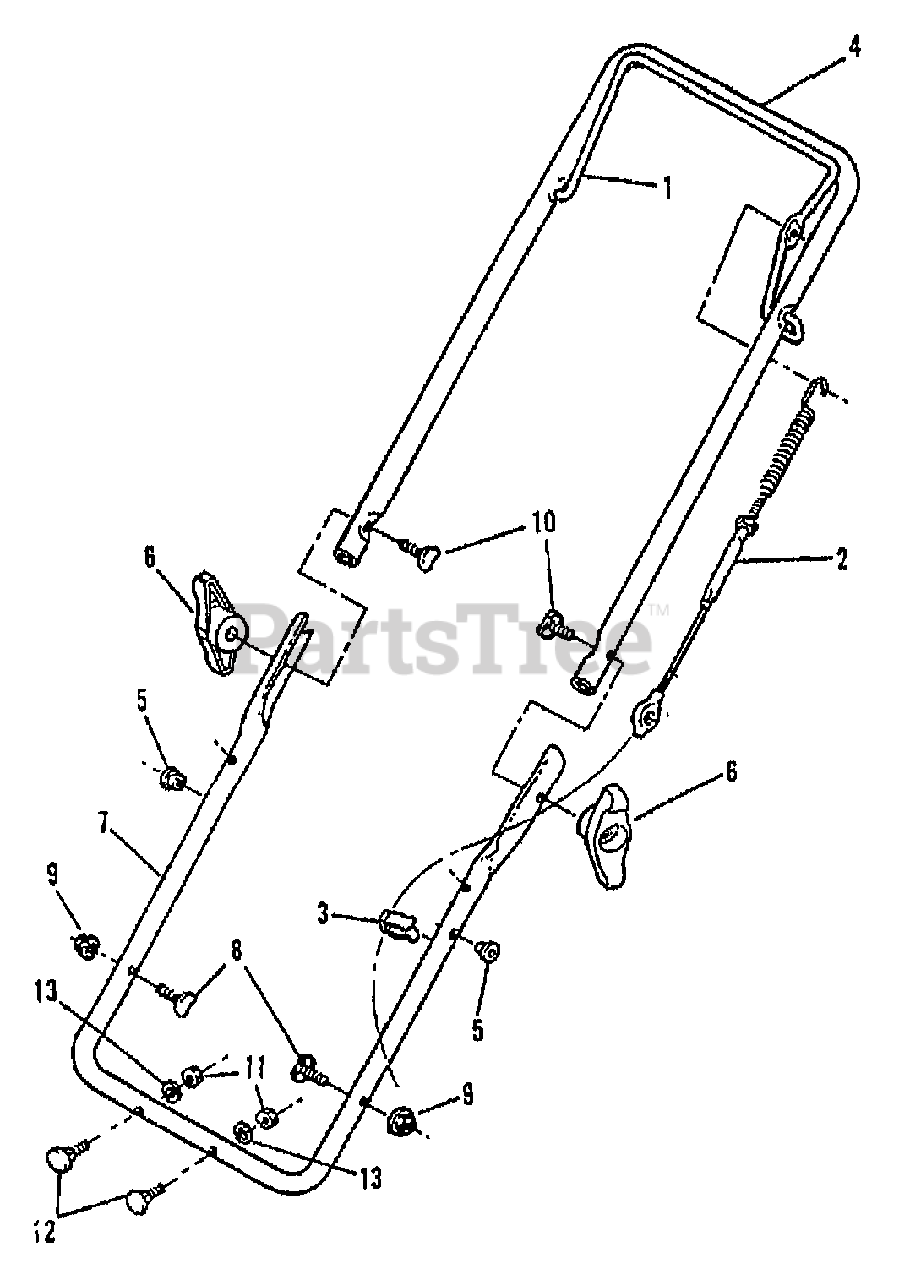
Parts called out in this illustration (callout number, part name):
1	BAIL-DRIVE CONTROL
2	CABLE-DRIVE CONTROL
3	CLIP-WIRE HARNESS
4	HANDLEBAR-UPPER
5	INSERT-NYLON
6	KNOB-CHUTE DEFLECTOR
7	HANDLEBAR-LOWER
8	SCR-CURV HD 5/16-18X1.375
9	NUT-HFLK 5/16-18
10	SCR-CURV HD 5/16-18X2
11	NUT-HEX 5/16-18
12	SCR-CARR 5/16-18X1.5
13	WASHER-LK 5/16
